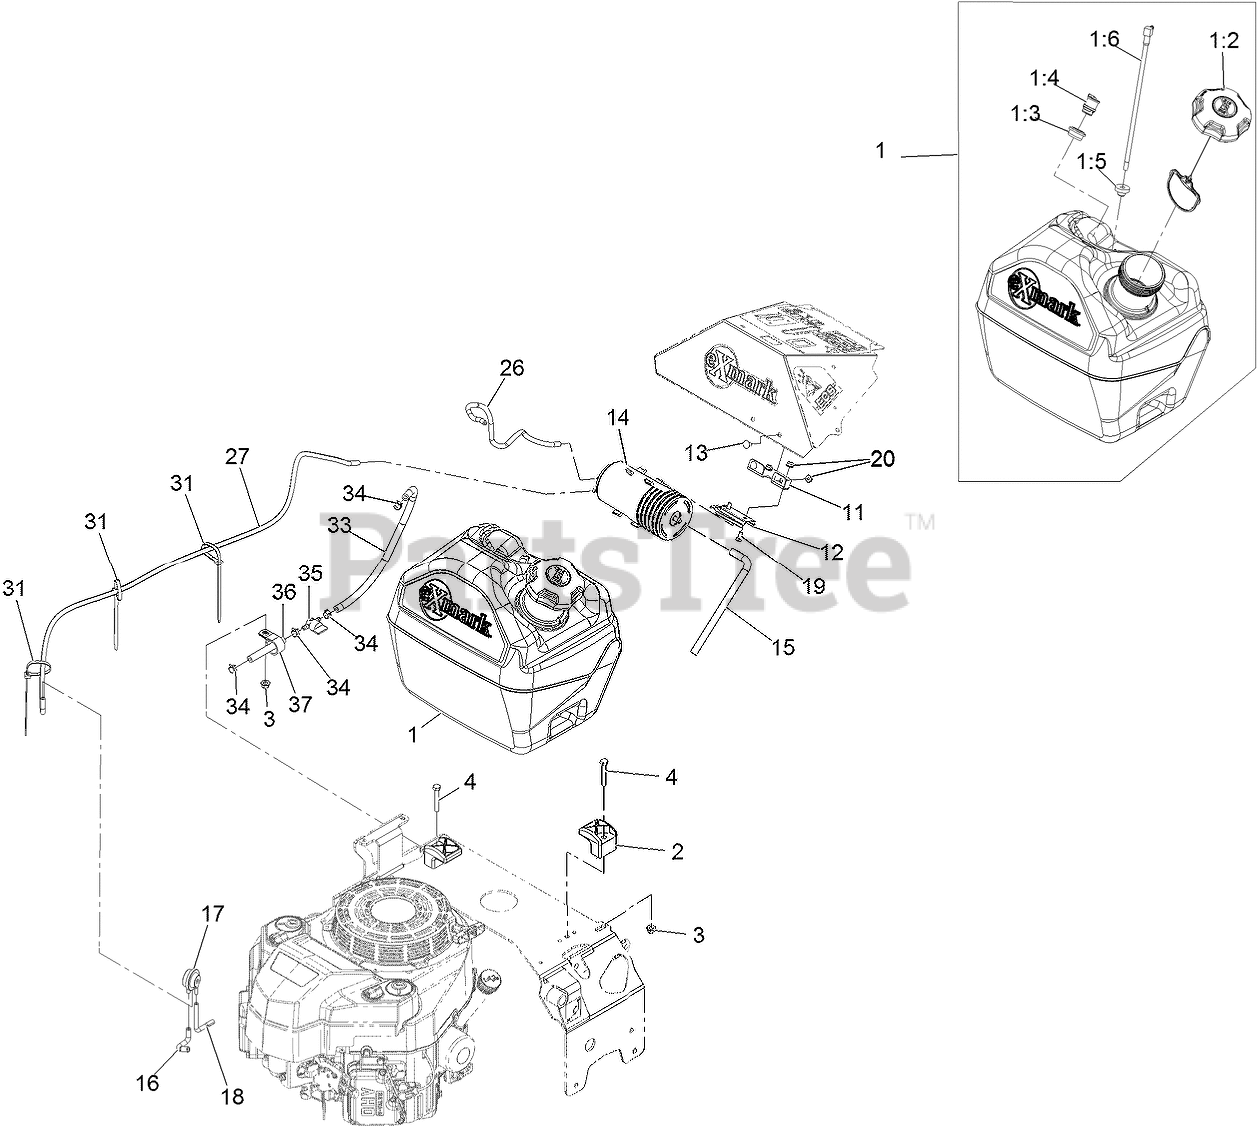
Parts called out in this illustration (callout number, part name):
1	ASM, FUEL TANK 5 GAL
1:2	CAP-FUEL, RATCHETING
1:3	GROMMET
1:4	VALVE-VENT, FUEL
1:5	BUSHING
3	NUT-HF, NI
4	SCREW-HH
11	BRACKET-CANISTER, CARBON
12	BRACKET-CANISTER, CARBON
13	SCREW-CARR
14	CANISTER-CARBON, 800CC
15	HOSE-VENT, CANISTER
16	HOSE-VENT, FORMED
17	VALVE-CONTROL, VACUUM
18	HOSE-VENT, FORMED
19	SCREW-HH
26	HOSE-EMISSIONS
27	HOSE-VENT, FORMED
31	TIE-PLASTIC
33	HOSE-FUEL
34	CLAMP-HOSE
35	VALVE-FUEL
36	HOSE-FUEL
37	CLIP-LOOM
